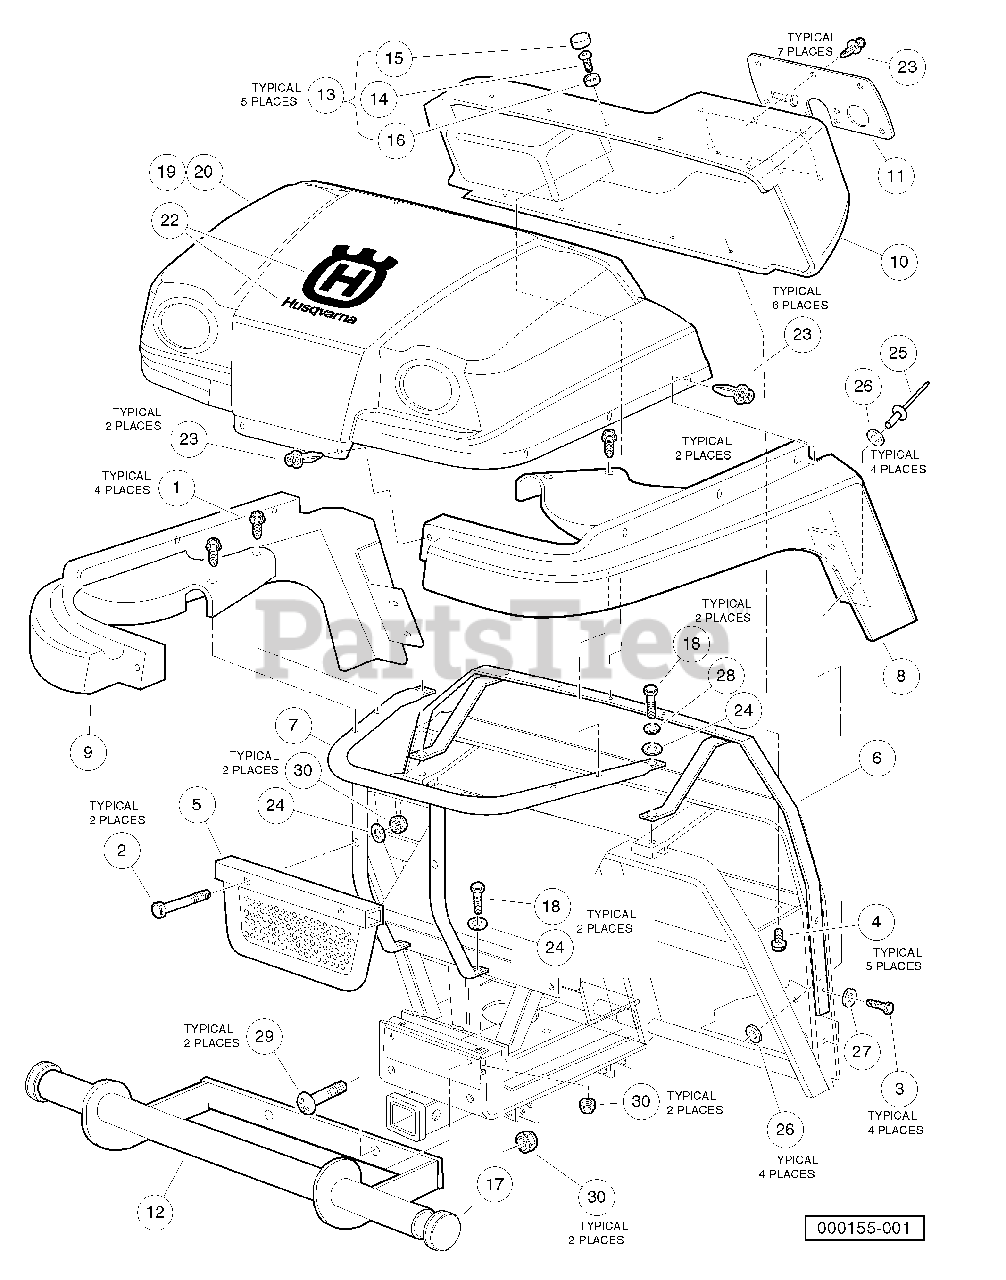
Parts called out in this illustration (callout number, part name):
1	Screw, Hex Washer Head 1/4-14 X .75
2	Screw, 5/16-18 X 2.50 Hex Cap
3	Screw, 1/4 X 0.625 Hex-Head
4	Screw, #12 X .50 Hex, Washer-Head
5	Grill Assembly
6	Support, Upper Cowl
7	Support, Lower Fender
8	Fender, Left Front
9	Fender, Right Front
11	Panel, Dash
12	Bumper Assembly
13	Kit, Dash Hardware
14	Screw, 1/4-20 X .75 Torx Pn Hd
15	Cap, 1/4" Plastic Screw Head
16	Washer, 1/4 Id Scalloped Plast
18	Screw, 5/16-18 X 2.50 Hex Cap
19	Cowl, Camo
20	Cowl, Orange
22	Decal, Husqvarna Cowl
23	Rivet, Removable, Tuflok 1/4"
24	Washer, 5/16 Type A Flat
25	Rivet, 3/16 X .500 Alum Pop
26	Washer, #10 Type A Flat
27	Washer, 1/4 Type A Narrow Flat
28	Lockwasher, 5/16 Split
29	Screw, 5/16-18 X 1.25 Truss Hd
30	Locknut, 5/16-18 Nylon Insert
